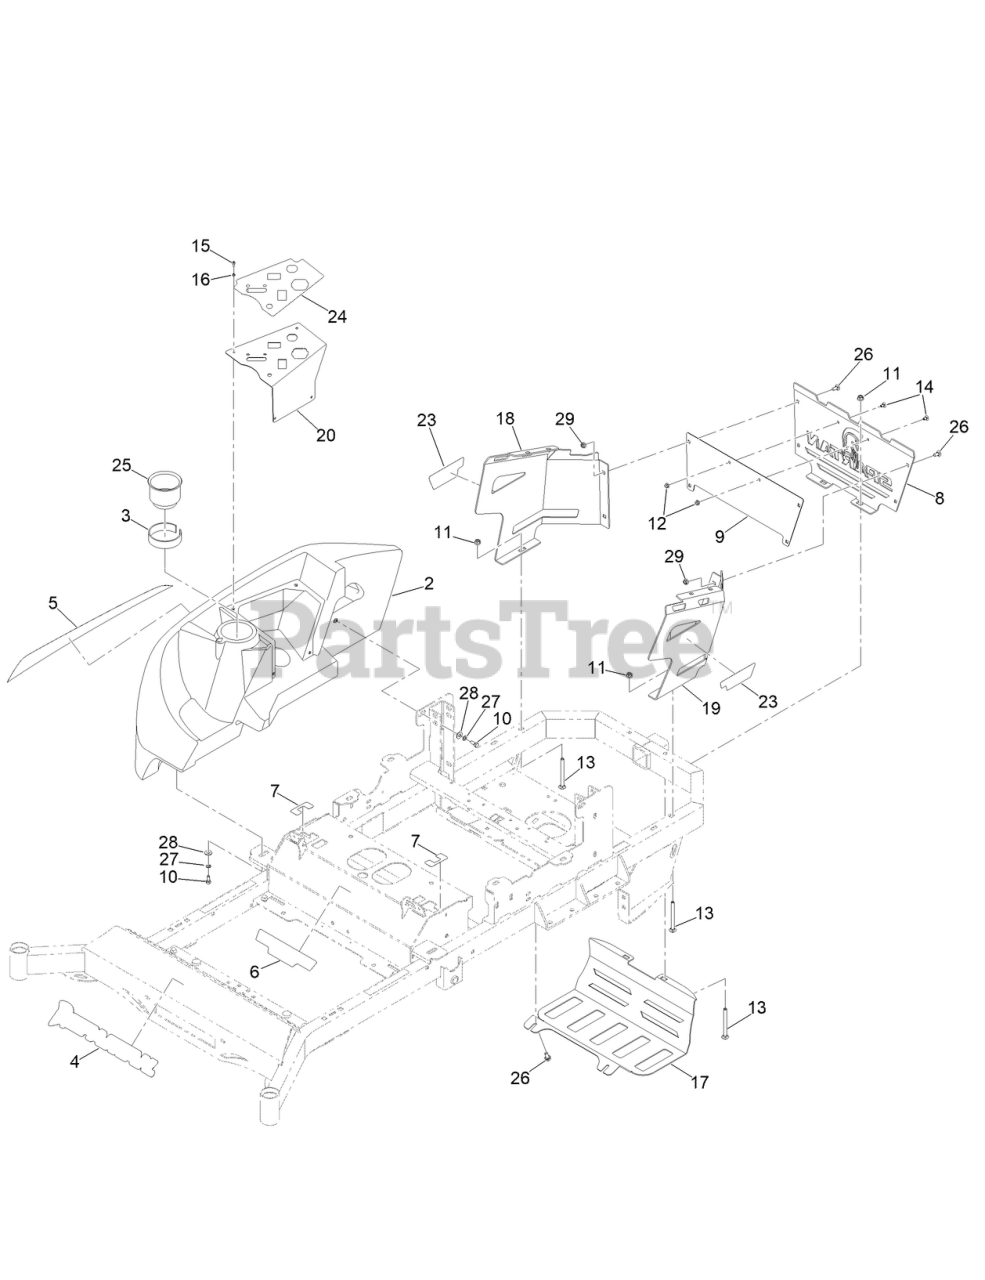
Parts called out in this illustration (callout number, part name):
2	CONSOLE W/ CUPHOLDER
3	TAPE-FOAM
4	DECAL-SPARTAN, FRONT
5	DECAL-TANK
6	DECAL-GT TRAC
7	DECAL-MOTION CONTROL
8	PLATE - ENGINE COWLING
9	PLATE -BACKER PLATE
10	SCREW-HH
11	3/8-16 NYLON INSERT FLANGE L/NUT YZ
12	1/4-20 HEX FLANGE NUT W/SERR ZINC
13	3/8-16 X 4 CARRIAGE BOLT ZINC
14	1/4-20 X 1/2 CARRIAGE BOLT,YZ
15	10-24 X 1/2 SOCKET C/S 18-8 SS
16	#10 SPLIT LOCKWASHER 18-8 SS
17	MUFFLER GUARD [GRAY]
18	2021 RT/SRT ENGN COWLING RTPAINTED
19	2021 RT/SRT ENGN COWLING LT PAINTED
20	RT 45 KEY MNT
23	DECAL-MODEL
24	DECAL-CONTROL PANEL
25	CUP HOLDER
26	BOLT-CARR
27	WASHER-LOCK
28	WASHER-FLAT
